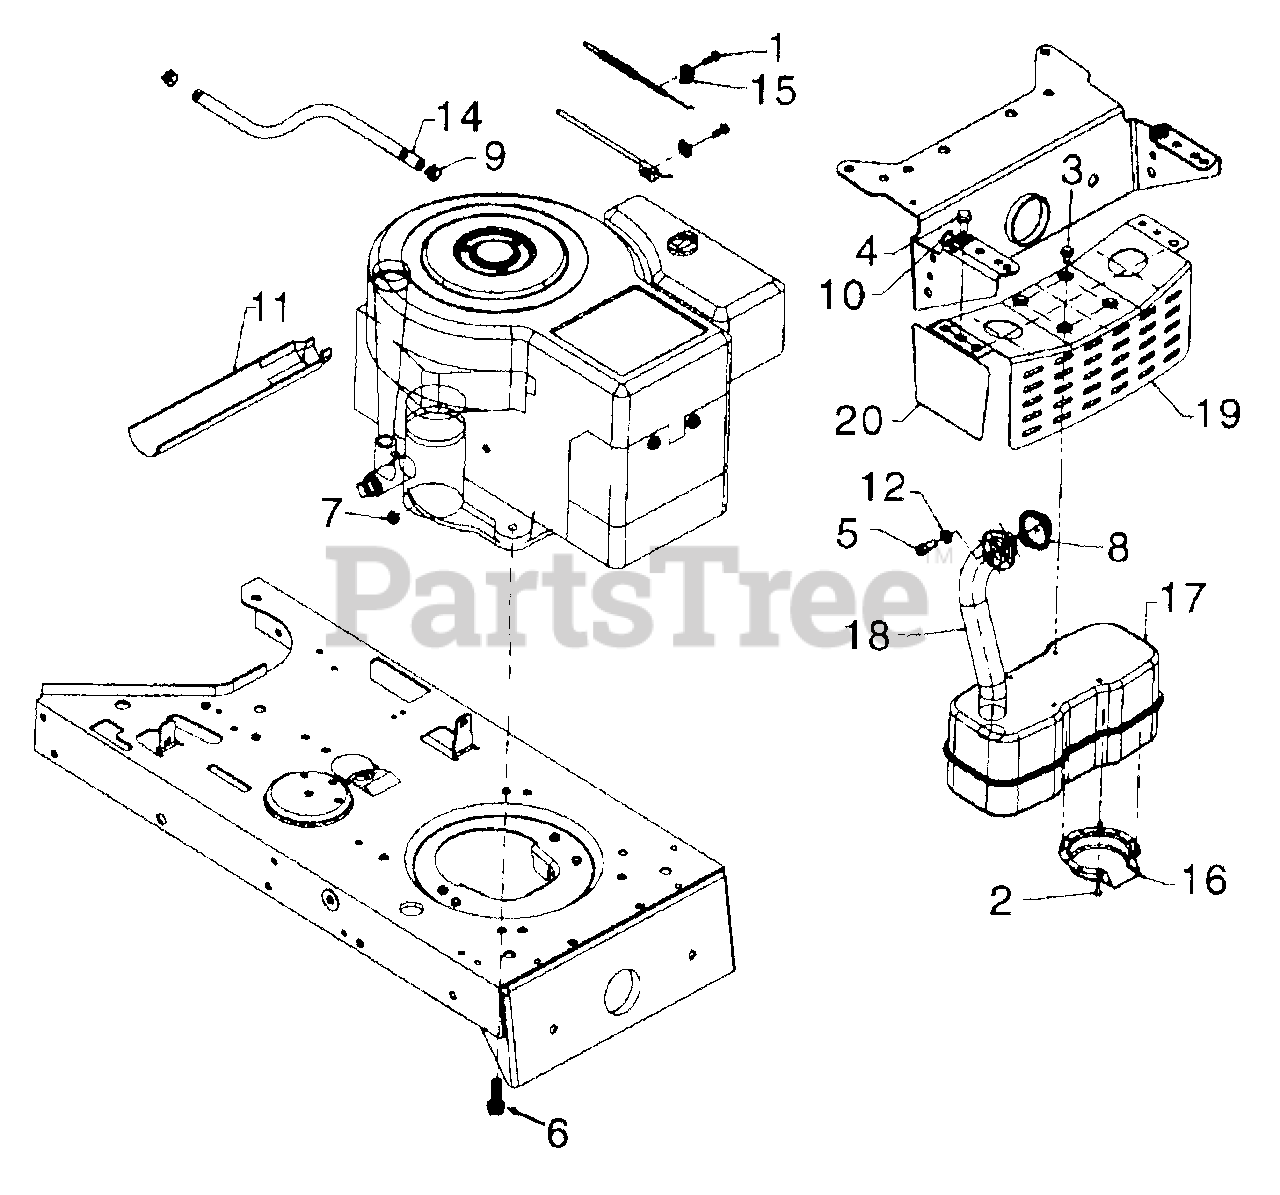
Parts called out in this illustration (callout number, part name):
1	Hex Wash. Scr. #10-32 x .62"
2	Hex Tap Scr. #8-32 x .38" Lg.
3	Hex TT-Tap Scr. 1/4-20 x .5" Lg.
4	Hex TT-Tap Scr. 5/16-18 x .62"
5	Socket Head Scr. 5/16-18 x .62"
6	Hex TT-Tap Scr. 3/8-16 x 1.25"
7	Hex Sems Scr. 1/4-20 Thd.
8	Gasket
9	Hose Clamp
10	Clamp
11	Oil Drain Sleeve
12	Lock Washer 5/16" I.D.
14	Fuel Line 12" Lg.
15	Casing Clamp
16	Muffler Deflector
17	Muffler
18	Exhaust Pipe
20	Shield Brkt.
